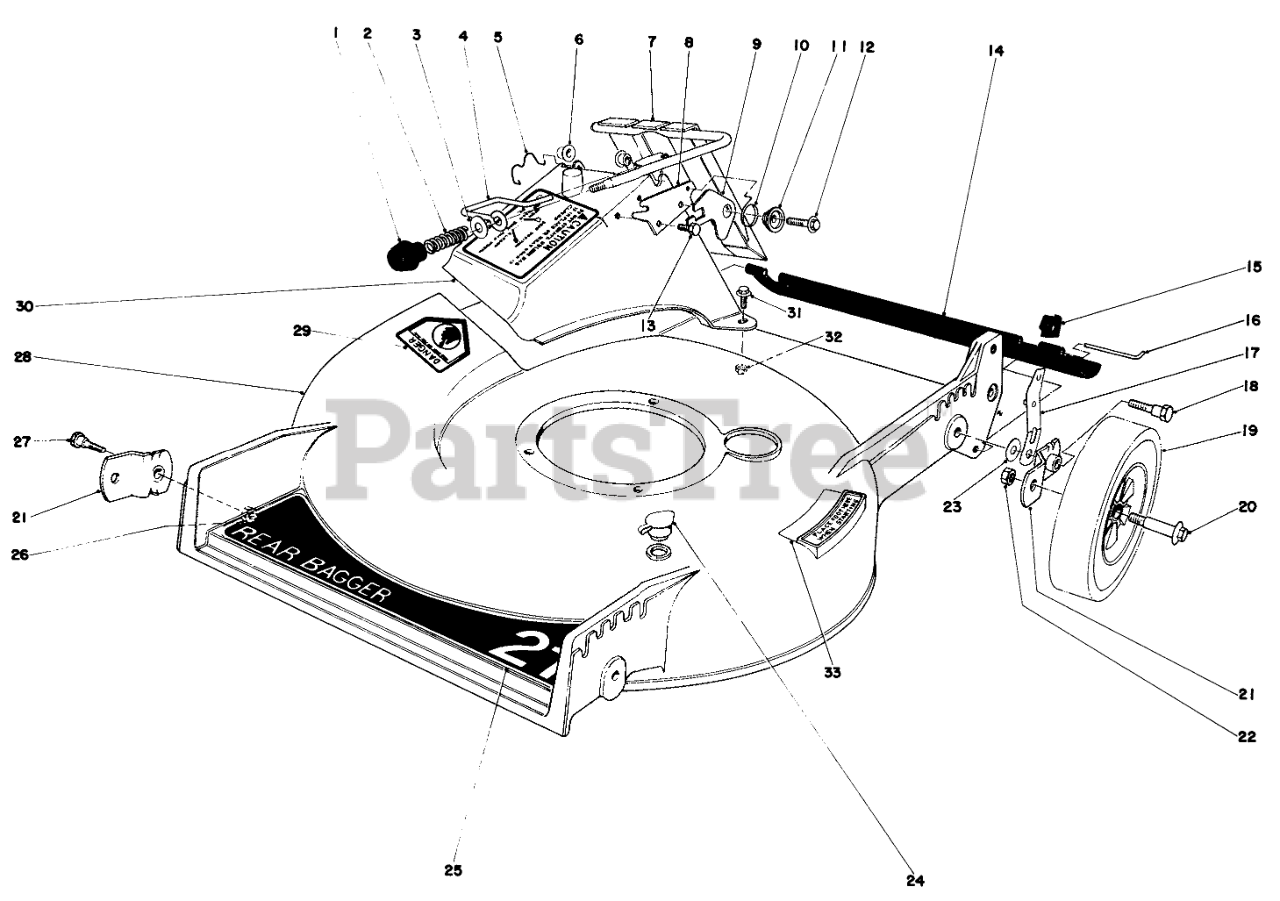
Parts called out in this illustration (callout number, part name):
2	COMPRESSION SPRING
3	WASHER
4	DOOR LATCH
5	DOOR RETAINER
6	BUSHING-NYLON
7	DOOR & HANDLE WA
8	DOOR LATCH PLATE
9	Latch Safety
10	TORSION SPRING
11	Latch Spacer
12	Screw
13	SCREW-HWH
14	SHIELD - TRAILING
15	KNOB-ARM
16	Rod Shield
17	SPRING ARM ASM (R&S)
18	5/16-18 PIVOT SCREW
19	WHEEL & TIRE ASM
20	BOLT-WHEEL
21	PIVOT ARM ASM A
22	Nut
23	WASHER-PIVOT
24	WASHOUT PLUG
25	Decal-Deck
26	Nut
27	PIVOT SCREW
28	Deck
29	DECAL-DANGER
30	DISCHARGE CHUTE B
31	SCREW-HH
32	NUT-LOCK, NI
